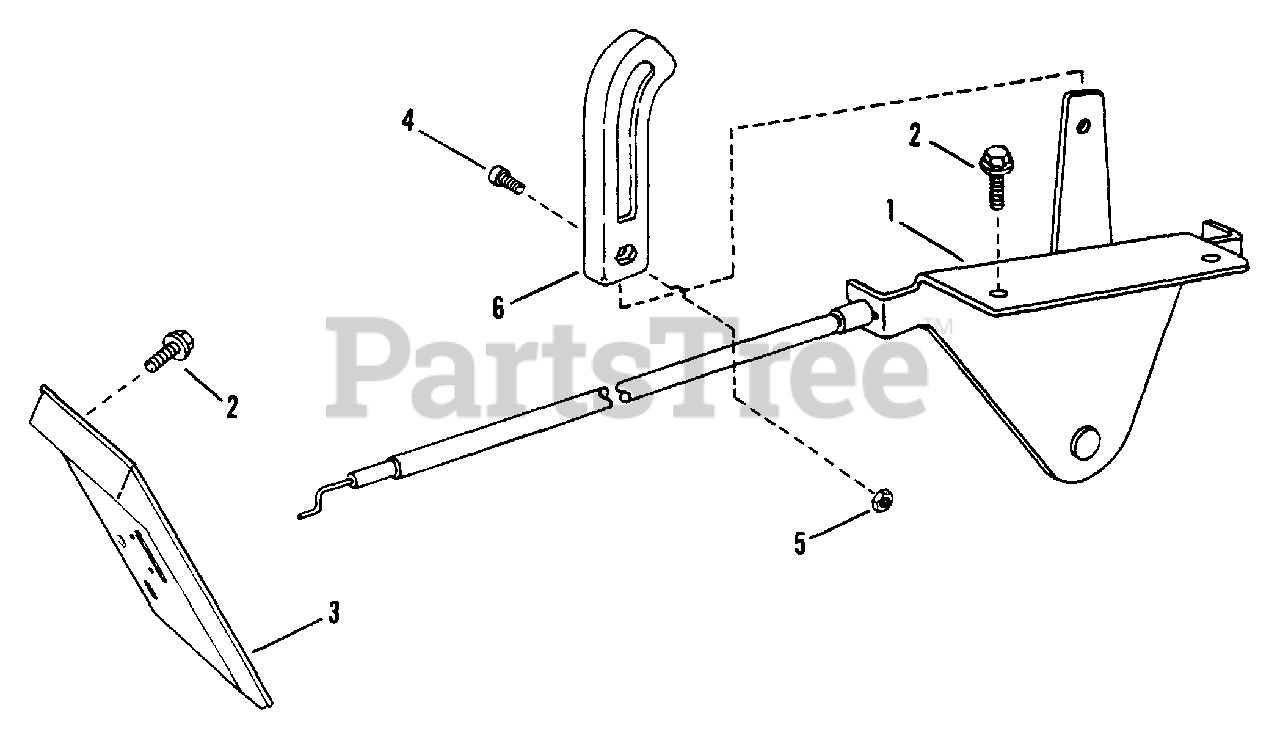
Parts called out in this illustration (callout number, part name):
1	CONTROL, Throttle
2	SCREW, #10-24 x 1/2" Hex Washer Self-Tap (Torx)
3	COVER, Dash Panel (Manual Start)
3	COVER, Dash Panel (Electric Start)
4	SCREW, #8-32 x 3/8" Cross Recess Filister
5	NUT, #8-32 Hex
6	KNOB, Throttle Control
